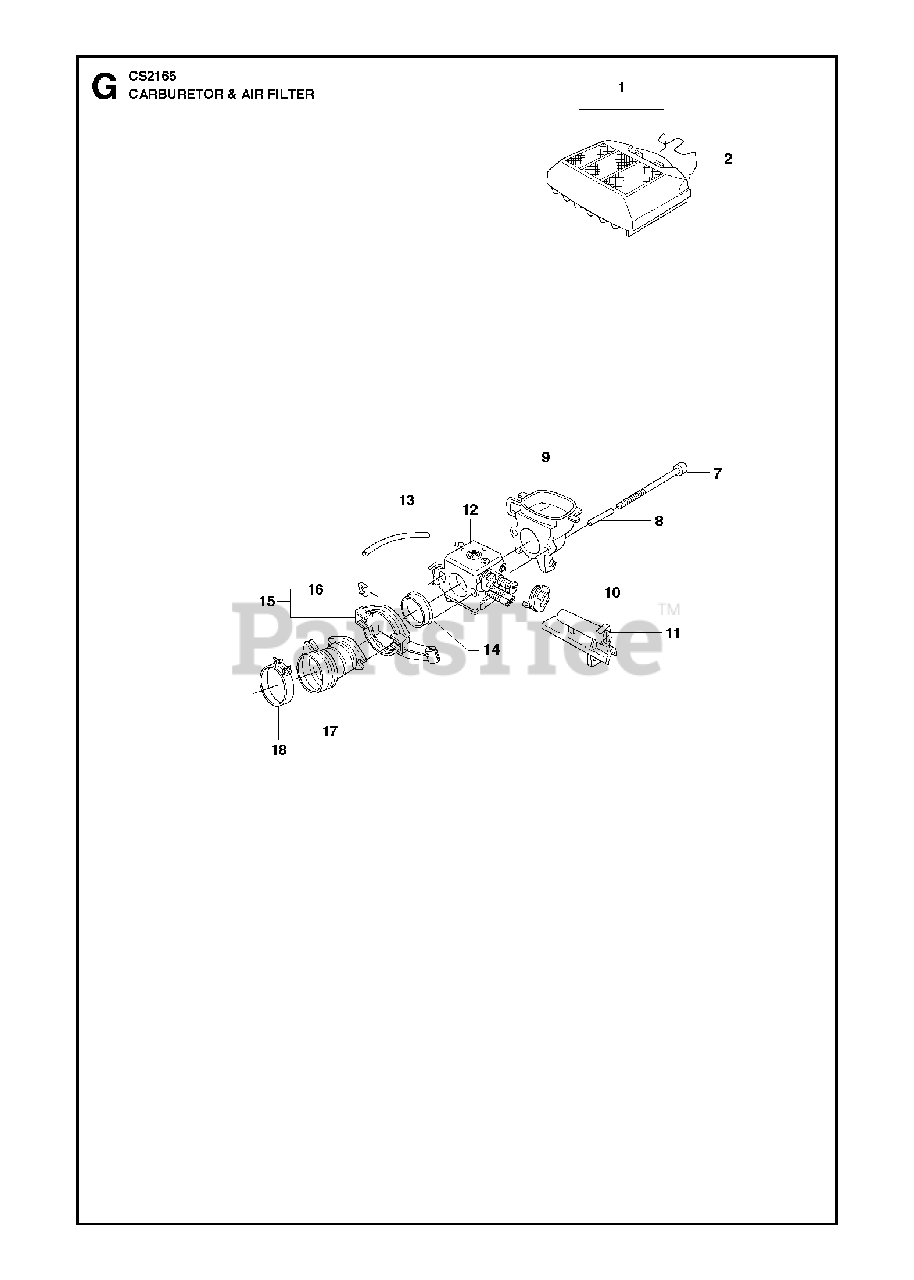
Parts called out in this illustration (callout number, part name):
1	AIR FILTER
2	AIR FILTER CLIP
11	SLEEVE
12	CARBURETOR WALBRO HD-6B
12	CARBURETOR HD-12B EPA WALBRO
16	NUT
17	INTAKE PIPE - EPA
18	CLAMP
